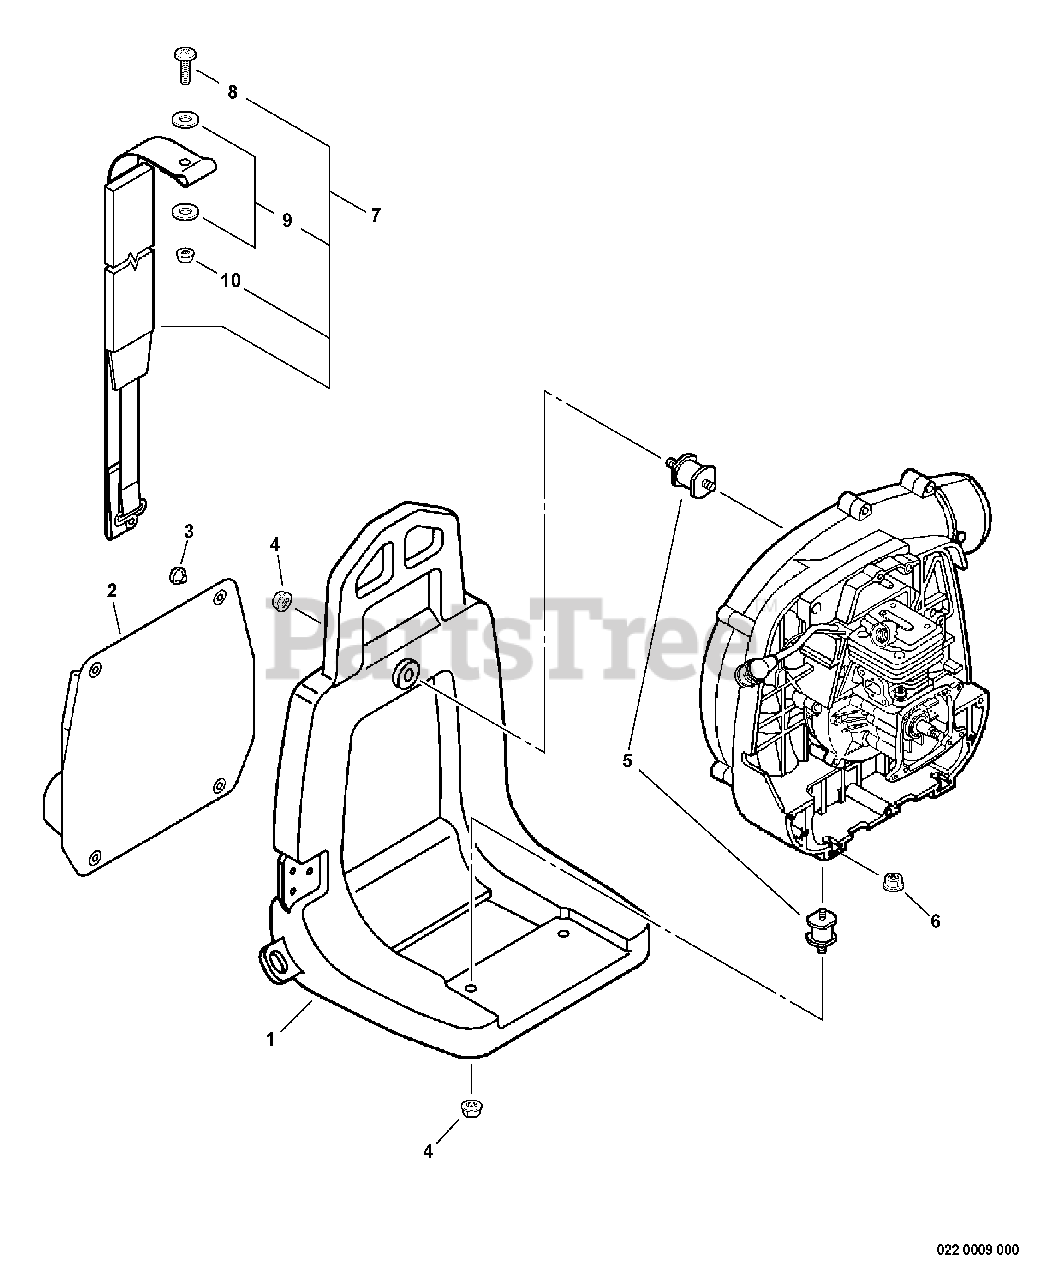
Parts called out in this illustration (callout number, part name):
1	FRAME, BACKPACK
2	CUSHION, BACKPACK
6	NUT, FLANGE M6
7	HARNESS, BACKPACK
8	SCREW 5×14
9	WASHER 5.5×18×1
10	NUT, FLANGE M5
